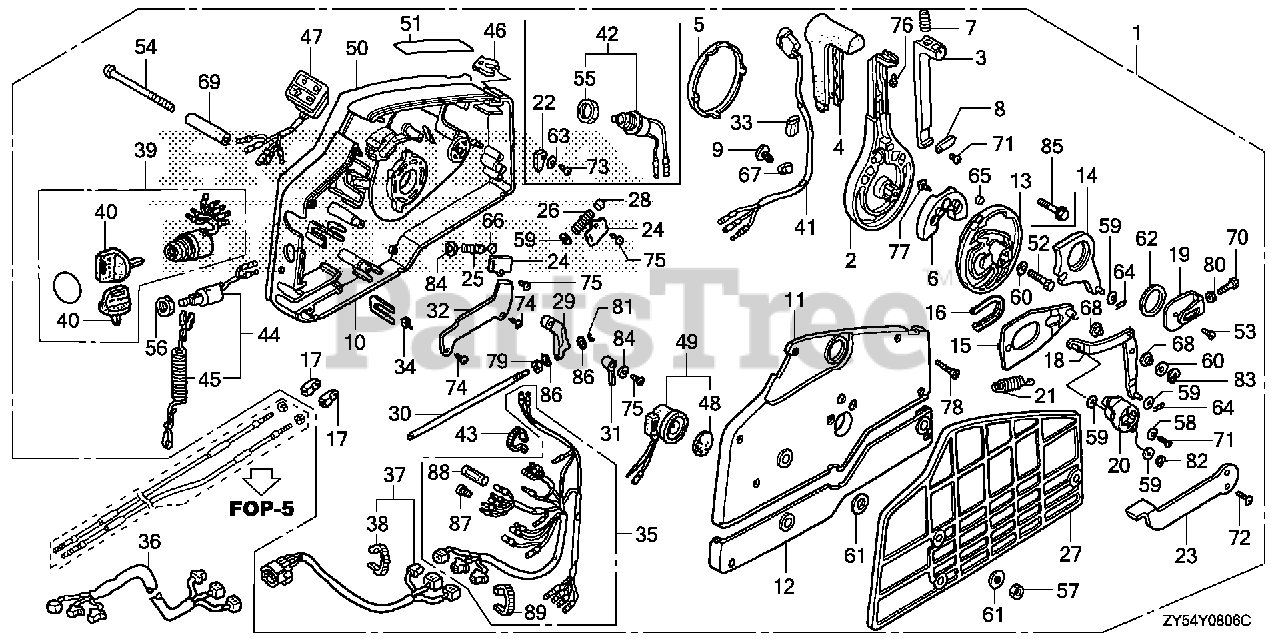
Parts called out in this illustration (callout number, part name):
1	BOX ASSY., REMOTE CONTROL (NHK MEC)
1	BOX ASSY., REMOTE CONTROL (P/T)(HI-LEX)
2	HANDLE, REMOTE CONTROL
3	LEVER, HANDLE LOCK
4	GRIP, REMOTE CONTROL HANDLE
5	CAP, HANDLE
6	BLOCK, NEUTRAL LOCK
7	SPRING, REMOTE CONTROL HANDLE
8	PLATE, LEVER SETTING
9	CLAMP, HARNESS
10	HOUSING, REMOTE CONTROL BOX (A)
11	HOUSING, REMOTE CONTROL BOX (B)
12	HOUSING, REMOTE CONTROL BOX (C)
13	WHEEL, CONTROL
14	ARM, SHIFT LINK
15	PLATE, SLIDING
16	COLLAR, SLIDING PLATE
17	PIVOT, SHIFT
18	ARM, LINK JOINT
19	BRACKET, LINK JOINT
20	WHEEL, ACCELERATOR
21	SPRING, ACCELERATOR WHEEL
22	CAM, STARTER SWITCH
23	LEVER, IDLE
24	PLATE, SPRING SETTING
25	SPRING, SHIFT CLICK
26	SPRING, CHOKE RETURN
27	SPACER, REMOTE CONTROL BOX
28	SPACER, CLICK SPRING
29	BLOCK, THROTTLE FRICTION
30	BOLT, FRICTION
31	SPACER, NEUTRAL SWITCH
32	CLAMP, POWER TILT CORD
33	PIPE, HARNESS GUIDE
34	SPACER, CABLE CLAMP
35	CABLE ASSY., REMOTE CONTROL (B)
36	CABLE ASSY., REMOTE CONTROL EXTENSION
37	CABLE ASSY., SWITCH PANEL
38	TIE, CABLE (2.4X92) (NATURAL)
39	SWITCH ASSY., COMBINATION
40	KEY ASSY., COMBINATION SWITCH (35100-ZV5-003 ONLY)
41	SWITCH ASSY., POWER TRIM-TILT
42	SWITCH ASSY., SOLENOID
43	BAND (BLACK 3.5X140)
44	SWITCH ASSY., EMERGENCY STOP
45	WIRE, EMERGENCY
46	CLIP, EMERGENCY LOCK
47	LAMP ASSY., INDICATION (2-LED)
48	PLATE, TURN SIGNAL BUZZER
49	BUZZER, WARNING
50	PLATE, REMOTE CONTROL (CAUTION PICT=SILVER)
51	MARK, FAST IDLE
52	BOLT, HEX. (8X35)
53	SCREW, PAN (6X10)
54	SCREW (6X95)
55	NUT, HEX. (20MM)
56	NUT, HEX. (16MM)
57	NUT, HEX. (6MM)
58	WASHER, PLAIN (5MM)
59	WASHER, PLAIN (6MM)
60	WASHER, PLAIN (8MM)
61	WASHER (6MM)
62	WASHER (28MM)
63	WASHER, PLAIN (4MM)
64	PIN, LOCK (6MM)
65	PIN (6X6)
66	ROLLER, CLICK
67	CLIP, WIRE HARNESS (6.3MM)
68	COLLAR, LINK JOINT
69	COLLAR, DISTANCE (6X10X43.5)
70	BOLT, HEX. (5X16)
71	SCREW, PAN (5X10)
72	SCREW, FLAT (5X12)
73	SCREW, TAPPING (4X10)
74	SCREW, TAPPING (5X8)
75	SCREW, TAPPING (5X10)
76	SCREW, TAPPING (5X12)
77	SCREW, TAPPING (6X16)
78	SCREW, TAPPING (5X25)
79	NUT, HEX. (6MM)
80	NUT, HEX. (5MM)
81	E-RING (3MM)
82	E-RING (4MM)
83	E-RING (7MM)
84	WASHER, PLAIN (5MM)
86	WASHER, PLAIN (4MM)
87	PLUG, CONNECTOR (INNER)
88	PLUG, CONNECTOR (OUTER)
89	TIE, CABLE (2.4X92) (NATURAL)
